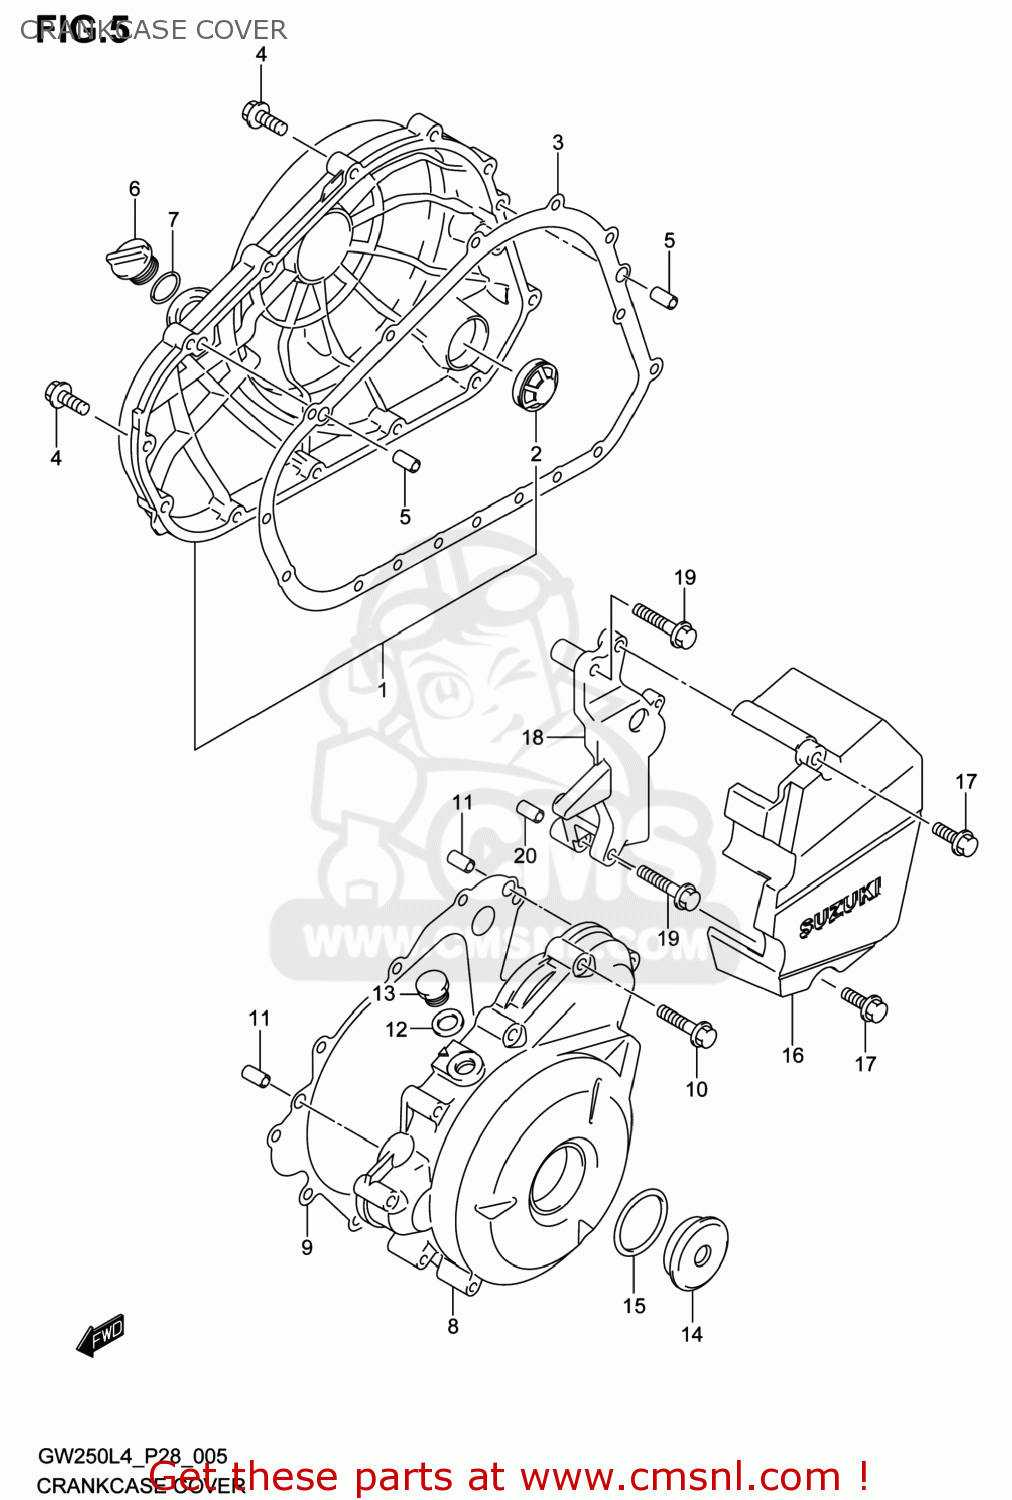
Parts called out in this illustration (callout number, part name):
1	COVER,CLUTCH
2	LENS,OIL LEVEL CHECK
3	GASKET,CLUTCH COVER (NAS)
4	BOLT
5	PIN
6	PLUG,OIL FILLER
7	O RING(D:3.1,ID:16.8)
8	COVER,MAGNETO
9	GASKET,MAGNETO COVER (NAS)
10	BOLT
11	PIN
12	GASKET,TDC PLUG (NAS)
13	PLUG,12X9
14	PLUG(SILVER)
15	O RING(D:3.1,ID:32.7)
16	COVER,ENGINE SPROCKET
17	BOLT
18	BRACKET,SPEED SENSOR
19	BOLT
20	PIN
